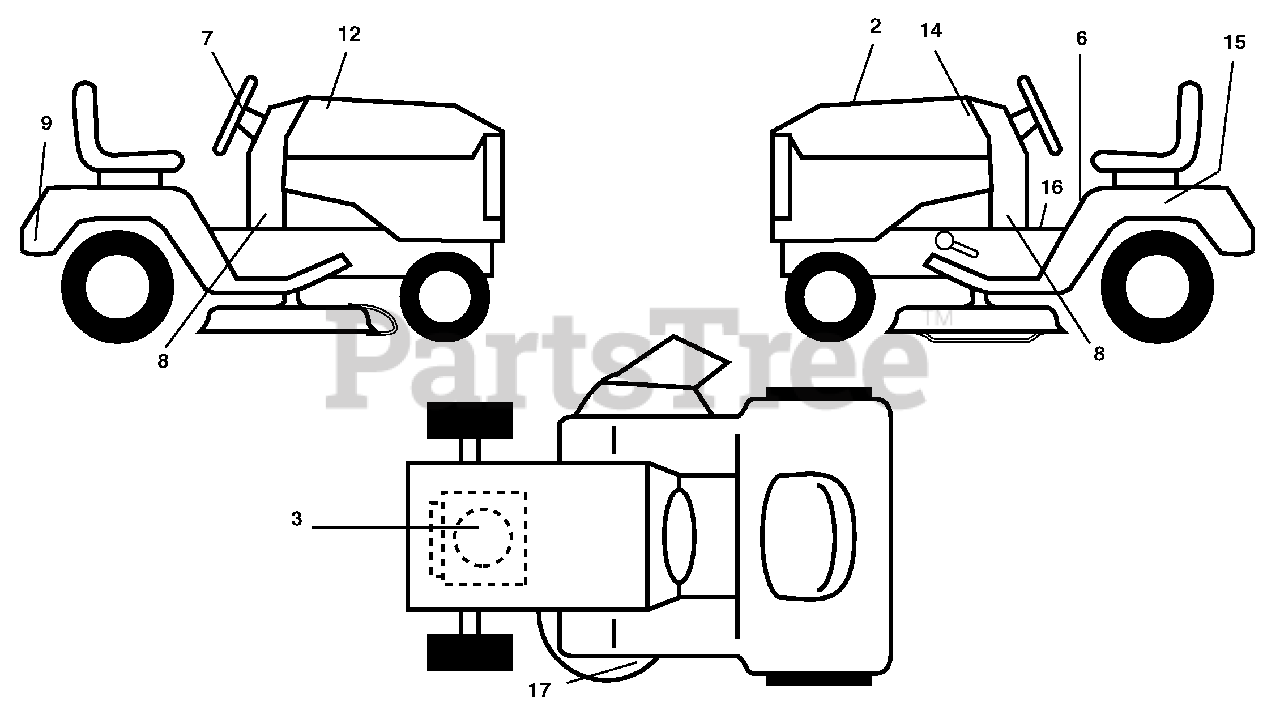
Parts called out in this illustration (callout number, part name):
2	Decal, Replacement
3	Decal, Engine HP
6	Decal, Fender Danger English
7	Decal, Ins Str Wh
8	Decal, LWRDASH
9	Decal, Fender
12	Decal, Hood RH
14	Decal, Hood LH
15	Decal, Caution, Battery
16	Decal, Fender
17	Decal, V-Belt Sch.
17	Decal, Handle Lft Height Adj.
17	Manual, Operator's E&SP
17	Manual, Parts E
